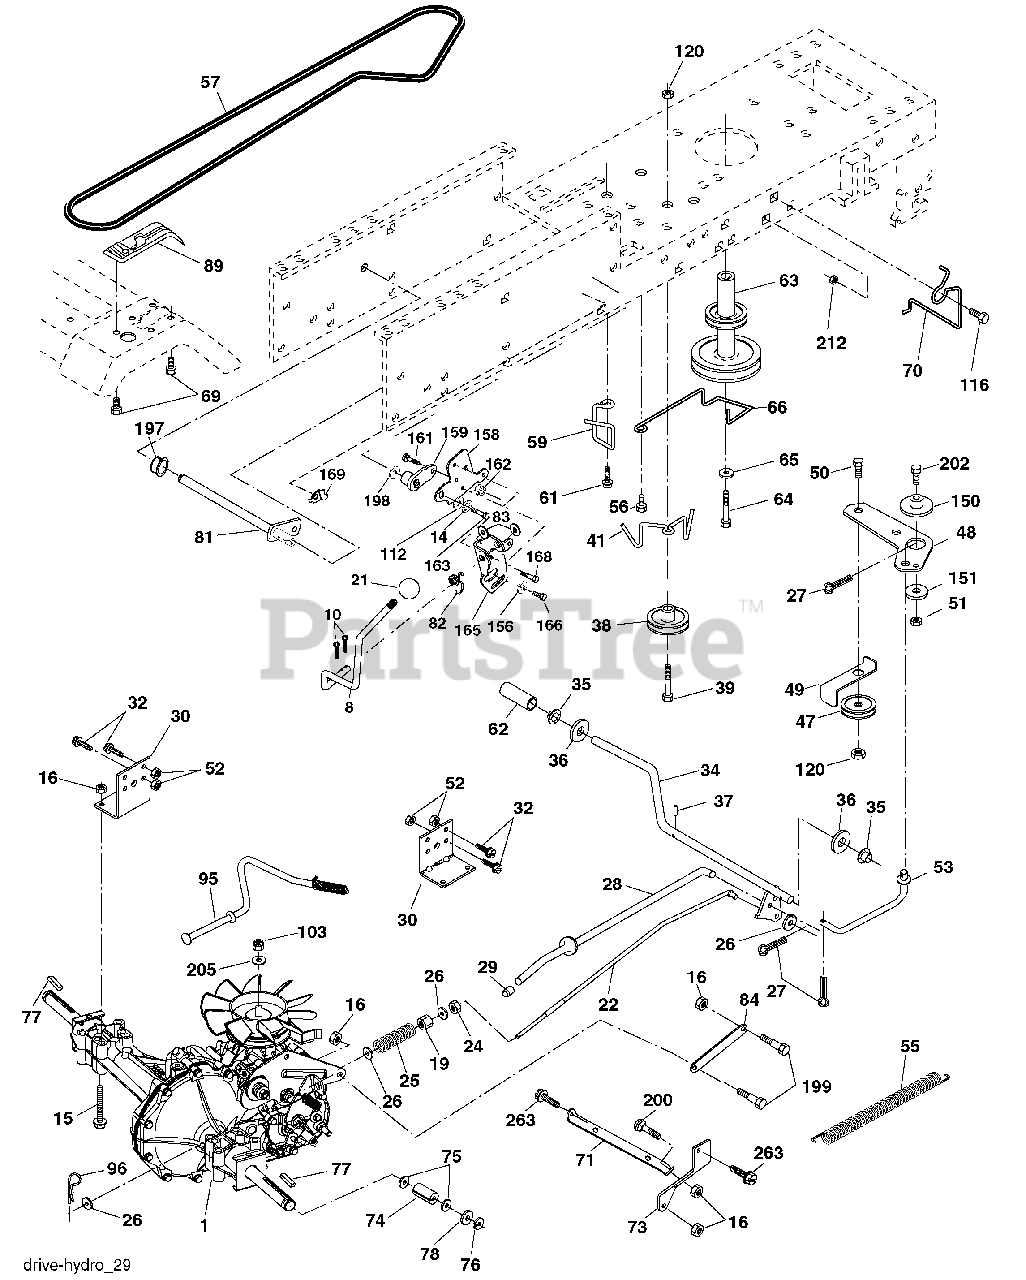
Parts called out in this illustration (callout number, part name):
8	Rod Shift
10	Pin Cotter 1/8 X 1
14	Washer Lock 1/4
15	Bolt Hex FLGHD 5/16-18 Gr. 5 unc
16	Nut Lock Hex w/ins 5/16-18 unc
19	Nut Lock Hex w/wsh 3/8-16 unc
21	Knob
22	Rod Brake
24	Nut
25	Spring Rod Brake
26	Washer 13/32 x 13/16 x 16 Ga.
27	Pin Cotter 1/8 x 3/4
28	Rod Brake Parking
29	Cap Brake Parking
30	Bracket Transmission
32	Bolt Hex Hd 5/16-18 unc x 3/4
34	Shaft Foot Pedal
35	Bearing Nylon
36	Washer
37	Pin Roll
38	Pulley Idler Composite
39	Bolt
41	Keeper Belt Idler
47	Pulley Idler V-Belt
48	Bellcrank Clutch Grnd Drustl
49	Retainer Belt
50	Bolt Carr. Sh. 3/8-16 x 1-1/2 Gr. 5
51	Nut
52	Nut Crownlock 5/16-28
53	Link Clutch
55	Spring Return Clutch
56	Screw 3/8-16 x 1-1/4
57	V-Belt Drive
59	Keeper Belt Center
61	Screw 3/8-16 x .875
62	Cover Pedal
63	Engine Pulley
64	Bolt Hex 7/16-20 x 4 x Gr. 5-1.5
65	Washer
66	Keeper Belt Engine Hydro
69	Screw Hex wsh HiLo 1/4 x 1/2 unc
70	Guide Belt Mower Drive RH
71	Strap Torque, LH
73	Strap Torque, RH
74	Spacer Axle
75	Washer 25/32 x 1 1/4 x 16 Ga.
76	Ring, E
77	Key Square
78	Washer 25/32 x 1-5/8 x 16 Ga.
81	Shaft Asm Cross
82	Spring Torsion
83	Washer 17/32 x 3/4 x 16 Ga.
84	Link Transaxle
89	Console Shift
95	Control Asm Bypass Hydro
96	Retainer Spring 1"
103	Nut, Hex Jam Top Lock 1/2-20 unf
112	Washer 9/32 x 3/4 x 10 Ga.
116	Bolt 3/8-16 x 1
120	Bolt Hex 3/8-16 x 1-1/2
150	Spacer Retainer
151	Washer 13/32 x 2 x 10
156	Washer 5/16 x 1.0 x 1.25
158	Bracket Shift Mount
159	Hub Tapered Flange Shift
161	Bolt Rdhd Sqnk 1/4-20 x 3/4 Gr. 5
162	Nut Crownlock 1/4-20 unc
163	Bolt Hex Fin 1/4-20 x 1
165	Bracket Pivot Lever
166	Screw 5/16-18 x 1.0 x .125
168	Bolt Shoulder 5/16-18 x .561
169	Plate Fastening
197	Nyliner Snap-In 5/8
198	Washer Nyliner 7/8 ID x .105 HYD
199	Bolt Shoulder 5/16-18 unc
200	Bolt Rdhd Sqnk 5/16-18 unc x 1
202	Bolt RdHd 3/8-16 unc x 1-1/2 Gr. 5
205	Washer 17/32 x 1 x 16 Ga.
212	Nut Hex flange Lock
263	Screw 3/8-16 x .75
